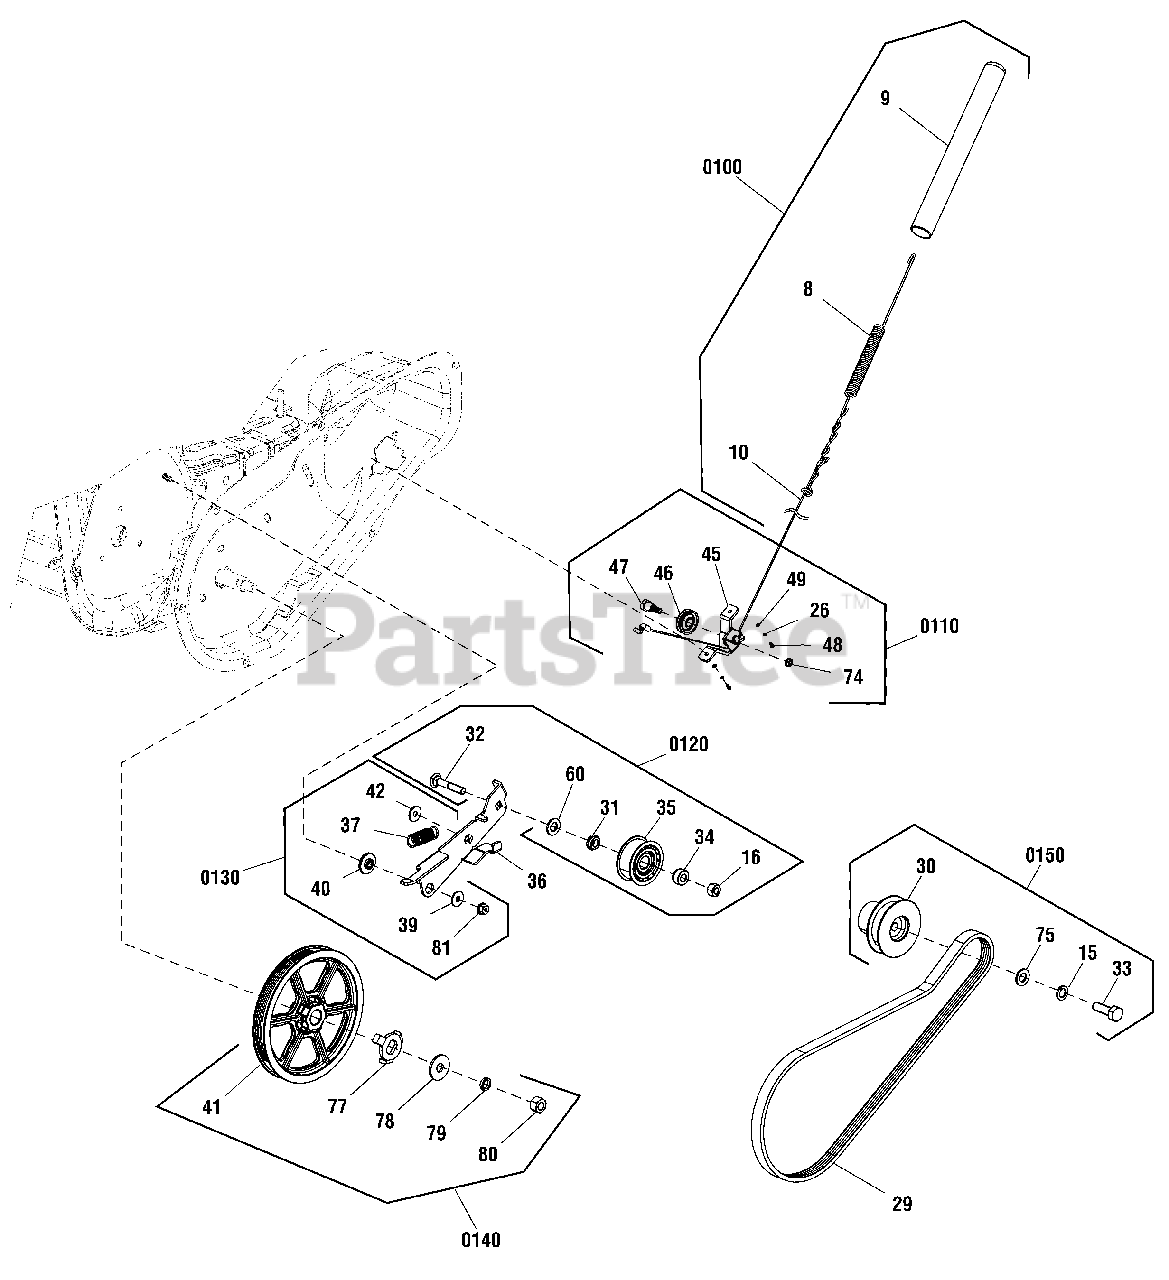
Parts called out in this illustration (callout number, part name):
8	*SPRING, Cable
9	*SLEEVE, Rubber
10	*CABLE, Auger
15	*WASHER, Spring, M10
16	*NUT, Lock, M8
26	*WASHER, Spring, M6
29	BELT, Drive
30	*PULLEY, Driver
31	*PAD
32	*BOLT, Carriage, M8x40
33	*BOLT, Hex 0.37-24x1.00
34	*SPACER, Idler Pulley
35	*PULLEY, Idler
36	PLATE, Tension
37	SPRING, Tension
39	*WASHER, Flat, 6x18x1.5
40	*SPACER, Idler Arm
41	*PULLEY, Driven
42	*WASHER, Flat, 8x22x2
45	*BRACKET, Cable Guide
46	*SPOOL, Cable, Auger Control
47	*SCREW, Hex Head Shoulder, M6x12
48	*SCREW, Hex Head, M6x12
49	*WASHER, Flat, 6x12x0.7
60	*WASHER, Flat, 10x20x1.8
74	*NUT, Flange Head, M6
75	*WASHER, Flat, 10x28x3
77	*CLAW, Coupling
78	*WASHER, Flat, 10x25x2
79	*WASHER, Spring, M10
80	*NUT, Lock, M10
81	*NUT, Flange Head, Lock, M6
0100	KIT, AUGER CABLE
0110	KIT, CABLE BASE, AUGER DRIVE
0120	KIT, IDLER PULLEY, TENSION PLATE
0130	KIT, HARDWARE, IDLER BRACKET
0140	KIT, AUGER PULLEY
0150	KIT, ENGINE PULLEY
